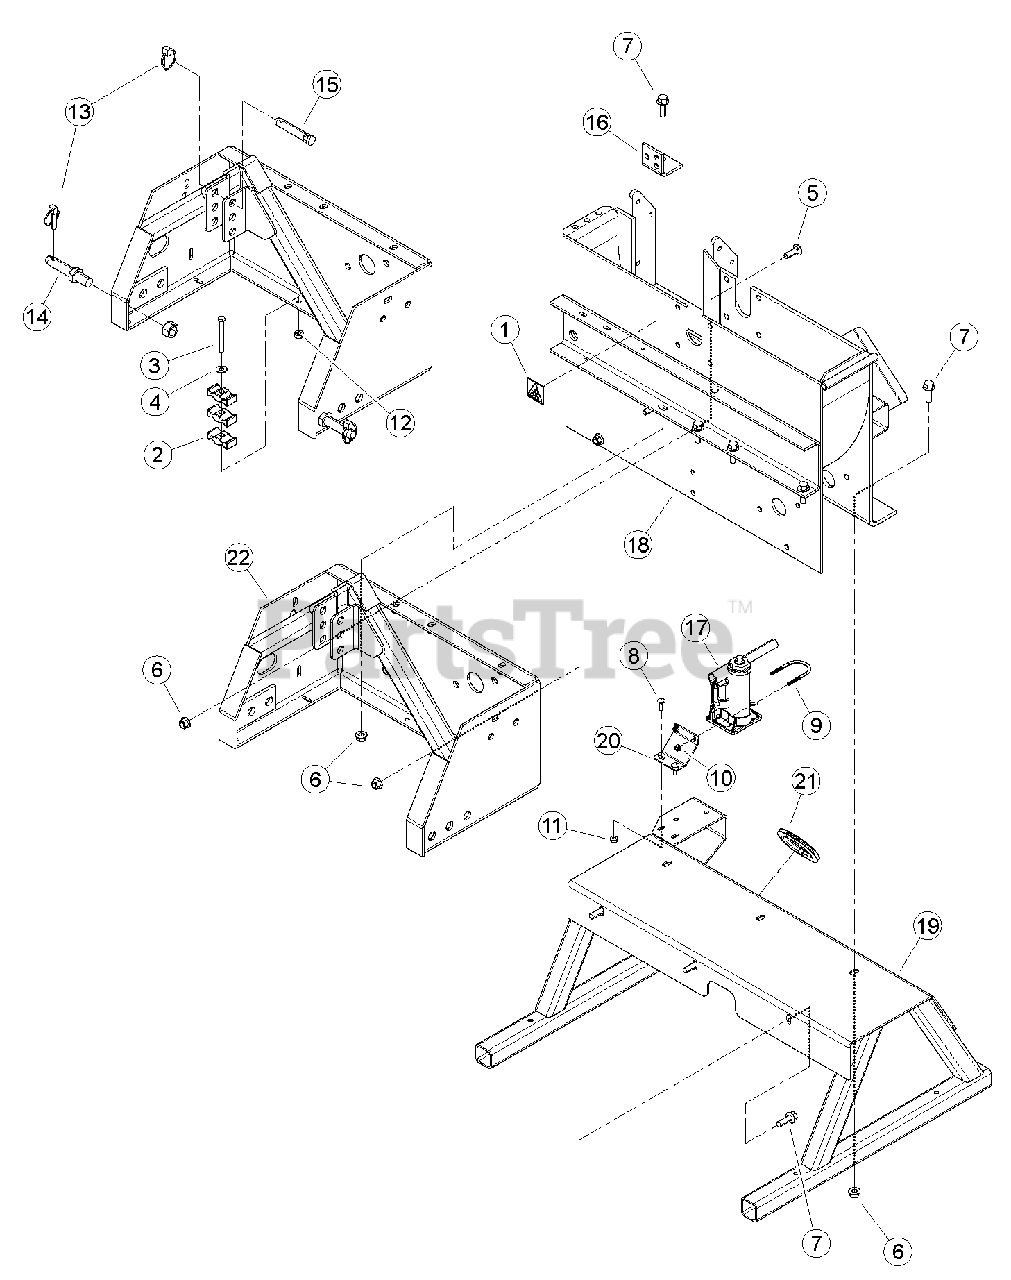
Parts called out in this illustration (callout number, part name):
1	DECAL, SHIELD DANGER ISO
2	CLAMP, PLASTIC HOSE
3	BOLT, 3/8 X 3-1/2" HEX HD GR5 ZP
4	WASHER, 3/8 FLAT
5	BOLT, 1/2 X 1-1/2" GR5 CRG ZP
6	NUT, 1/2-13 NYLOCK FLANGE
7	BOLT, 1/2-13 X 1-1/2 GR5 FLANGE NC
8	BOLT, 5/16-18 X 1 GR5 CRG
9	U-BOLT, 1/4 X 1-1/2 PIPE
10	NUT, 1/4-20 NYLOCK FLANGE
11	NUT, 5/16-18 NYLOCK FLANGE
12	NUT, 3/8-16 NYLOCK FLANGE
13	PIN, 7/16 X 1-1/4 LYNCH
14	PIN, LIFT ARM 7/8 X 5" LG
15	PIN, TOP LINK 3/4 X 4-1/2" LG
16	ANGLE, LOWER SHOCK
17	JACK, HYDRAULIC 2 TON
18	WELDMENT, CHIPPER BOTTOM
19	WELDMENT, PTO STAND
20	PLATE, JACK MOUNT
21	TRIM, SLOT EDGE COVER
22	WELDMENT, HITCH SUPPORT
